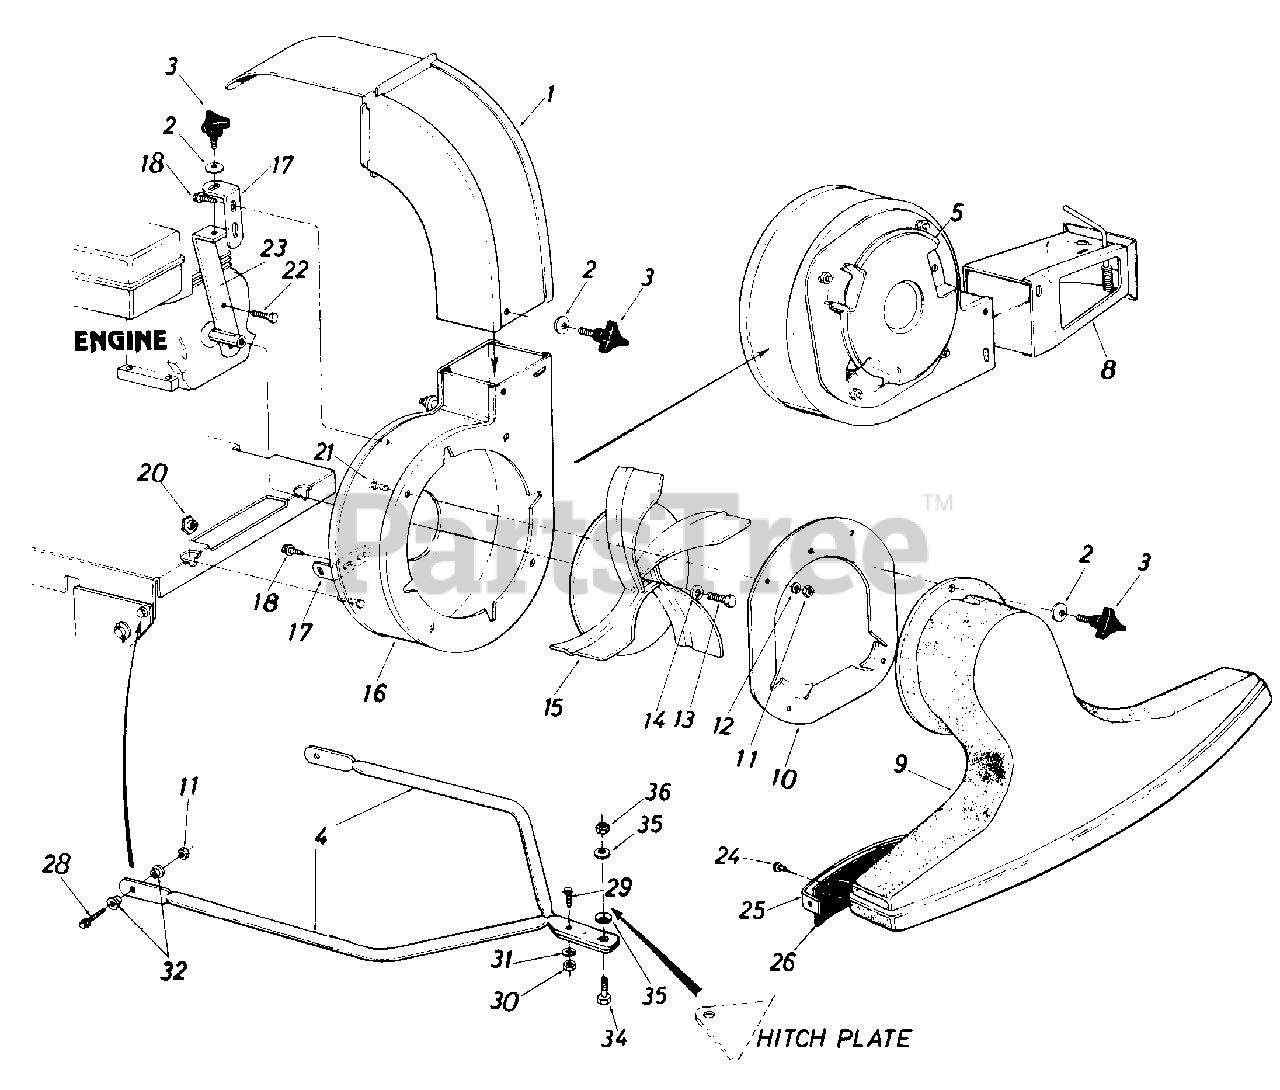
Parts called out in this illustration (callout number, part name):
3	3-Arm Thumb Scr. 5/16-18 x .75" Lg.
10	Nozzle Plate Ass'y.
11	Hex Nut 5/16-18Thd.
12	L.-Wash. 5/16" I.D.
13	Hex Bolt 3/8-24 x 1.25" Lg.
14	L.-Wash. 3/8" I.D. H.D.
15	Air Vane Plate Ass y.
16	Blower Housing Complete
20	Hex Shoulder Nut .50 I.D.
21	Carriage BoIt 5/16-18 x .62" Lg.
22	Hex Locking Bolt 5/16-24 x .75" Lg.
28	Hex Bolt 5/16-18 x 1.00" Lg.
29	Truss Mach. Scr. 1/4-20 x .75" Lg.
30	Hex Nut 1/4-20 Thd.
31	L.-Wash. 1/4" I.D.
32	Shoulder Spacer
34	Shld. Bolt .496 Dia.
35	Belleville Wash. .39 I.D. x 1.12 O.D.
36	Hex Jam L-Nut 3/8-16 Thd.
